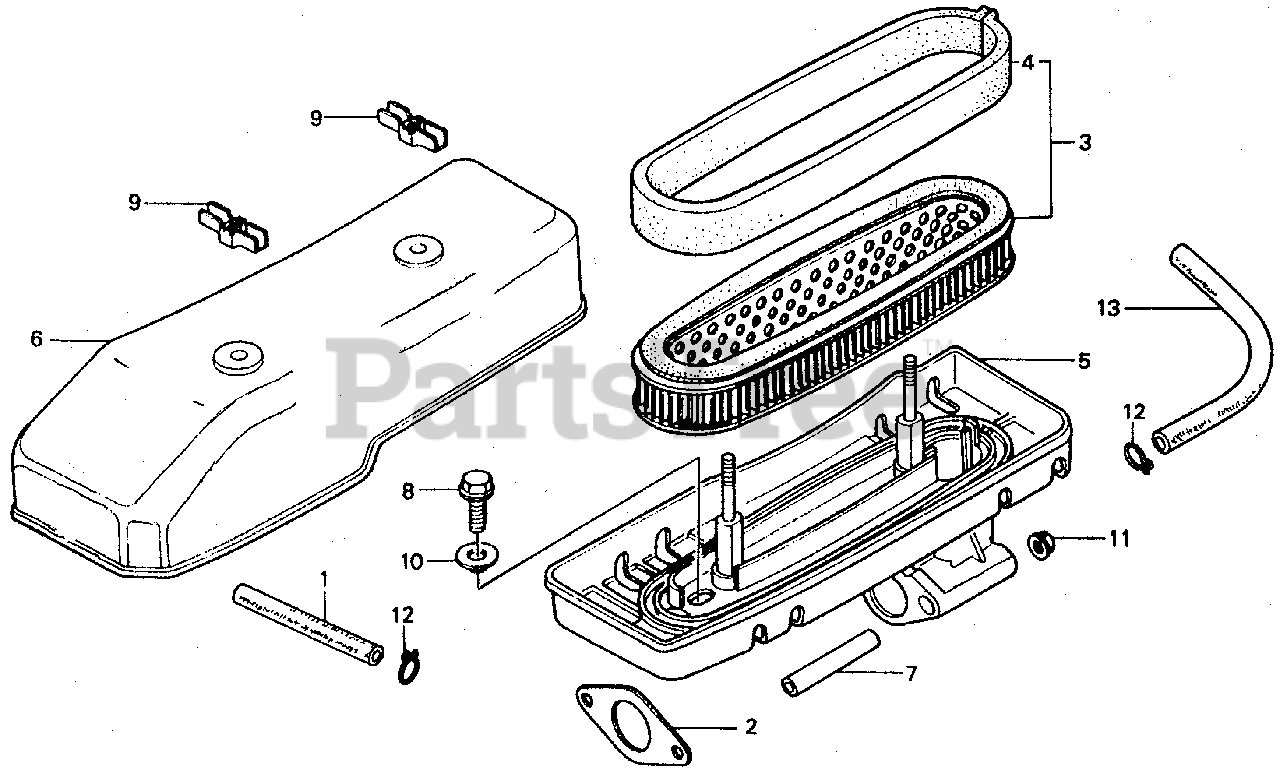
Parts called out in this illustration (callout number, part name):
2	GASKET, AIR CLEANER
3	ELEMENT, AIR CLEANER
4	FILTER (OUTER)
5	HOUSING, AIR CLEANER (NOT AVAILABLE)
6	COVER, AIR CLEANER
7	COLLAR, AIR CLEANER HOUSING (NOT AVAILABLE)
8	BOLT, FLANGE (6X12) (CT200)
9	NUT, AIR CLEANER COVER (DACRO COATING)
10	WASHER, HEADLIGHT CASE
11	NUT, FLANGE (6MM)
12	CLIP, TUBE (B12.5)
13	BULK HOSE, VACUUM (7.3X1000) (7.5X160)
